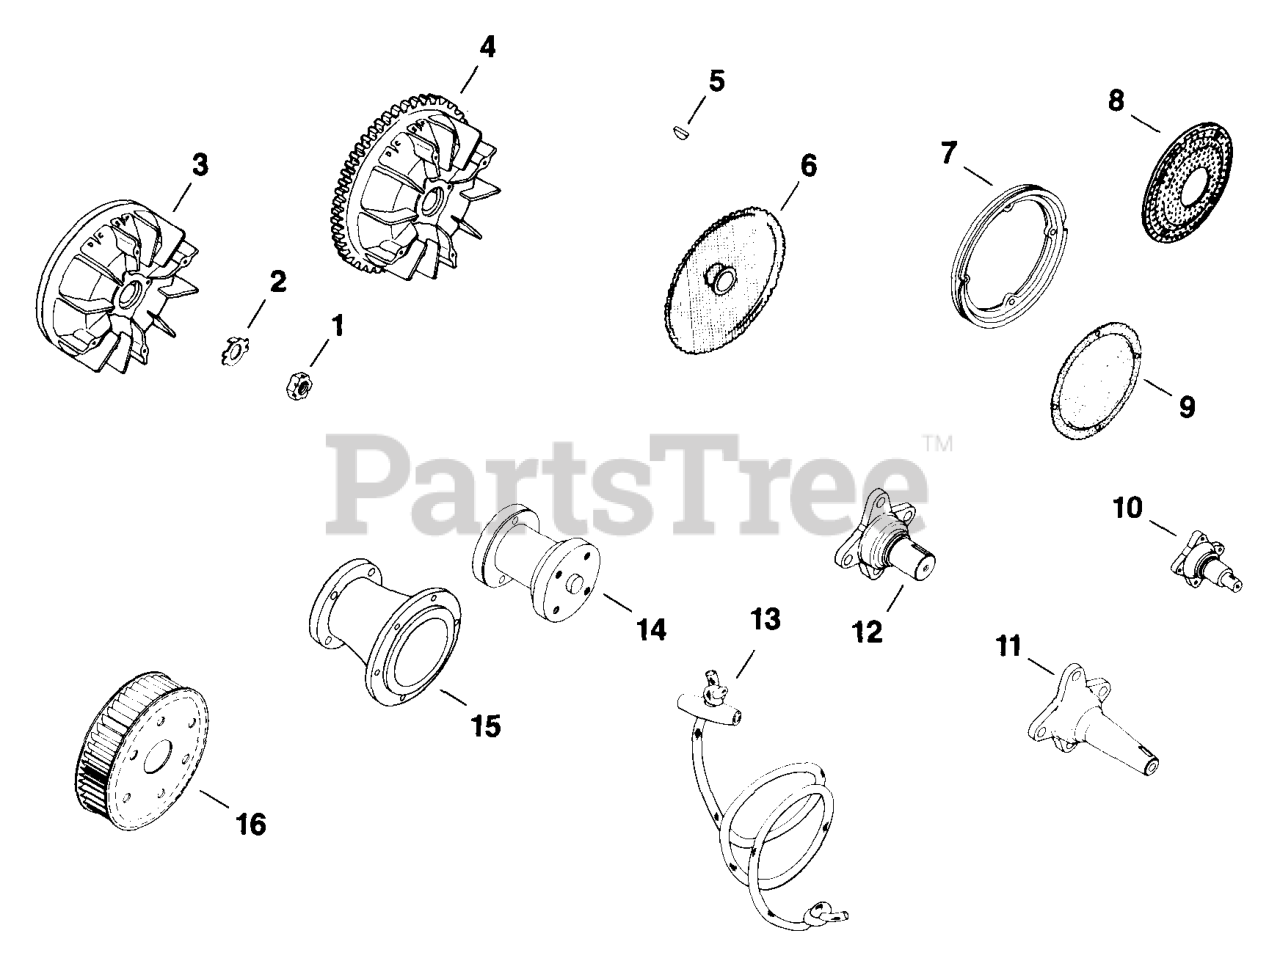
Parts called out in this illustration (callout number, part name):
4	FLYWHEEL - DISCONTINUED
5	KEY, 1/4" X 1"
9	SCREEN - (#DSC)
13	ROPE-DISCONTINUED
